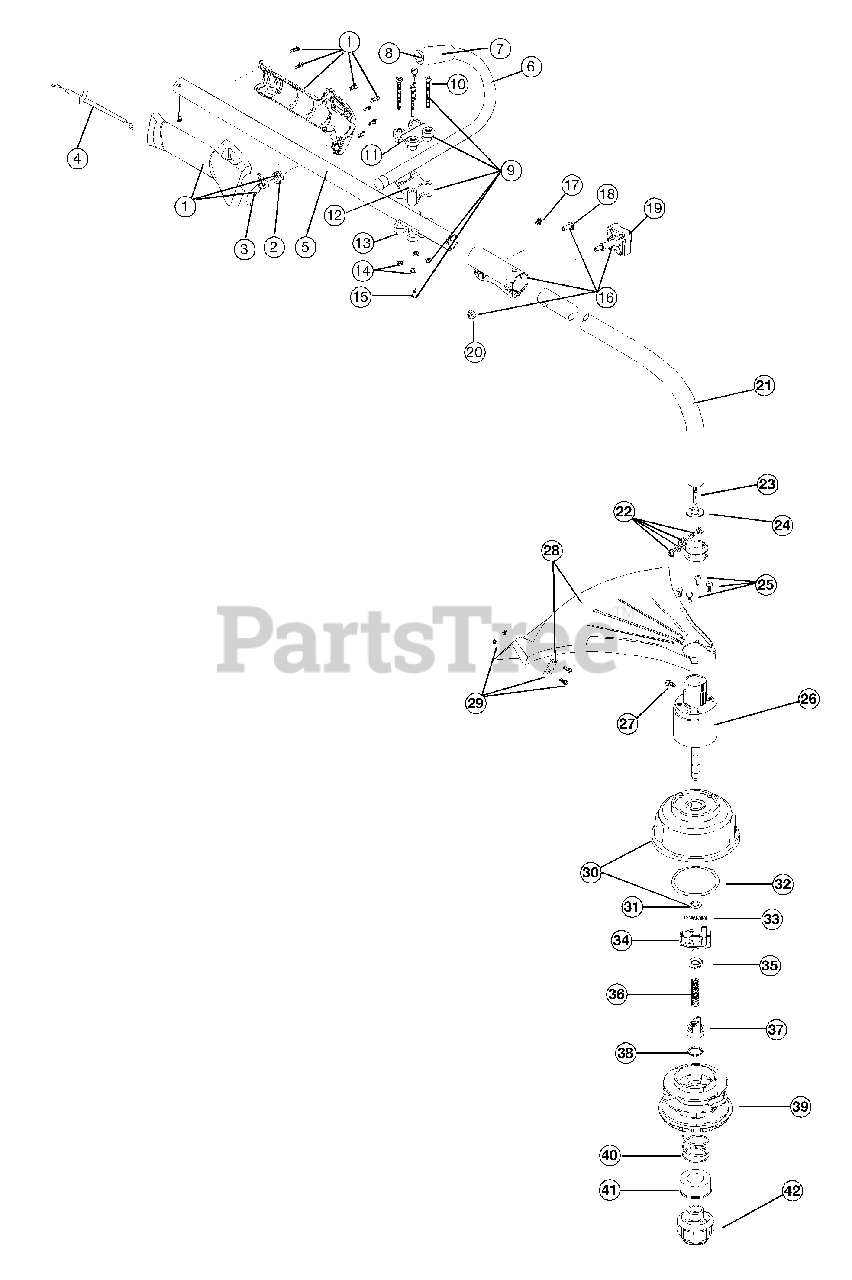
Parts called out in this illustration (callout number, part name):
1	Throttle Housing & Trigger Assembly
2	Throttle Trigger Spring
3	Throttle Trigger
4	Throttle Cable Assembly
5	Upper Drive Shaft Housing Assembly
6	J-Handle Assembly
8	Tube Closure
9	Handle Bracket Assembly
11	Upper Handle Clamp
12	Middle Handle Clamp
13	Lower Handle Clamp
15	Anti-Rotation Screw
16	Click-Link Coupler
19	Adjustment Knob
20	Knob Retaining Nut
21	Lower Drive Shaft Housing Assembly
22	Lower Clamp Assembly
23	Lower Flexible Drive Shaft
24	Palnut
25	Shield Mounting Screw
26	Bushing Housing Assembly
27	Anti-Rotation Screw
28	Shield and Blade Assembly
29	Blade Assembly
30	Outer Spool Assembly w/ Retainer
31	Retainer
32	Thrust Washer
33	Small Spring
34	Slider
37	Plunger
39	Inner Reel
40	Large Spring
41	Foam Seal
42	Bump Head Knob Assembly
